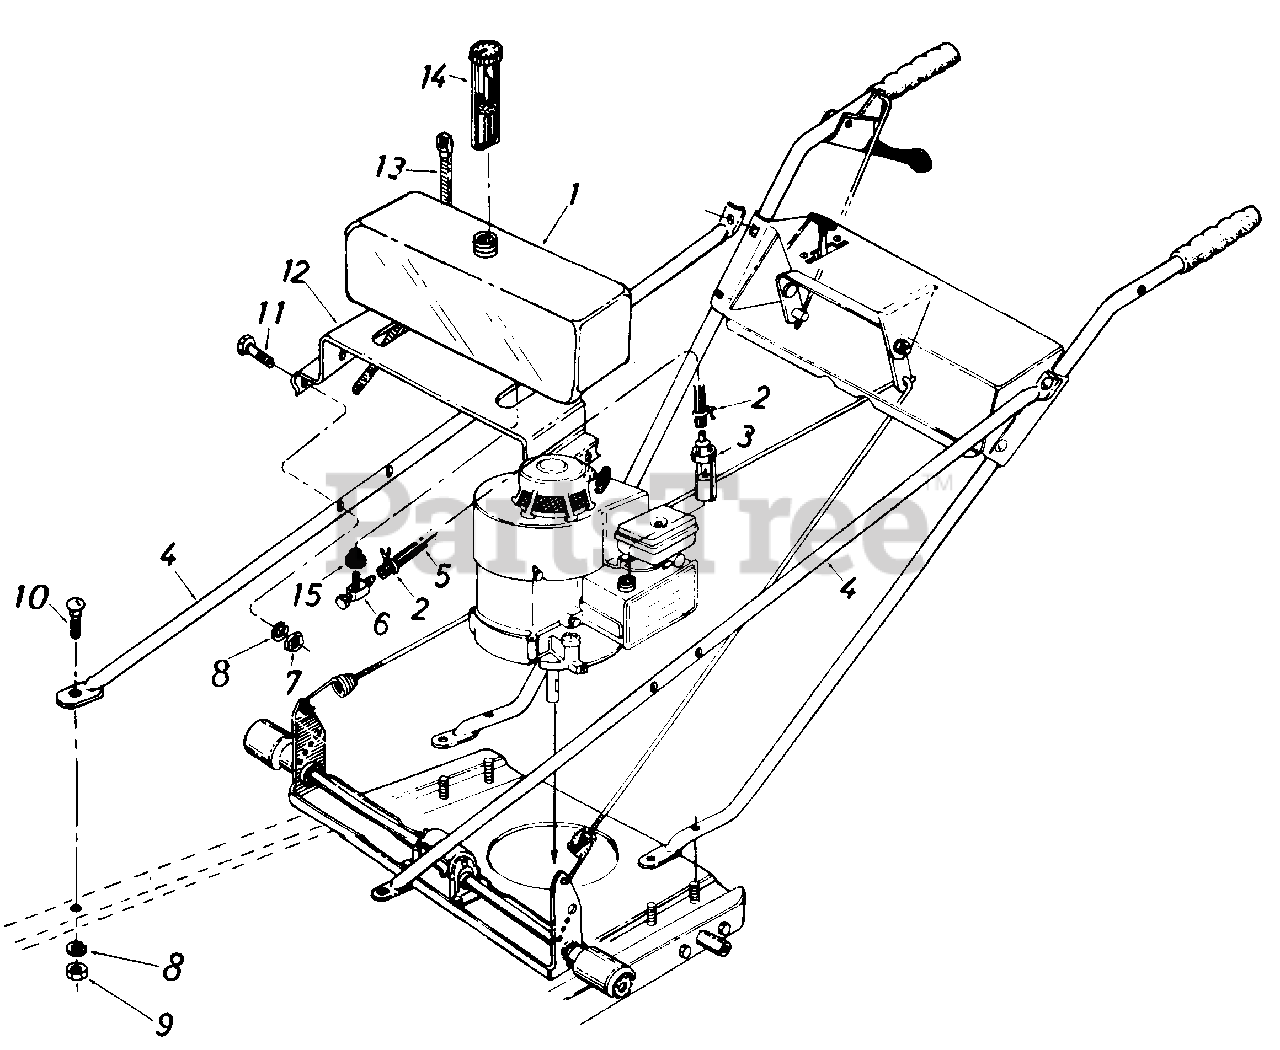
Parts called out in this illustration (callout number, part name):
1	Fuel Tank
2	Hose Clamp 3/8" I.D.
3	Fuel Control Valve
5	Fuel Line
6	Fuel Tank Fitting
7	Hex Nut 5/16-24" Thd.
8	L-Wash. 5/16" I.D.
9	Hex Nut 5/16-18" Thd.
10	Carriage Bolt 5/16-18 x .62" Lg.
11	Hex Bolt 5/16-24 x 1.25" Lg.
12	Fuel Tank Mntg. Brk't.
13	Cable Tie
14	Fuel Gauge
15	Bushing
